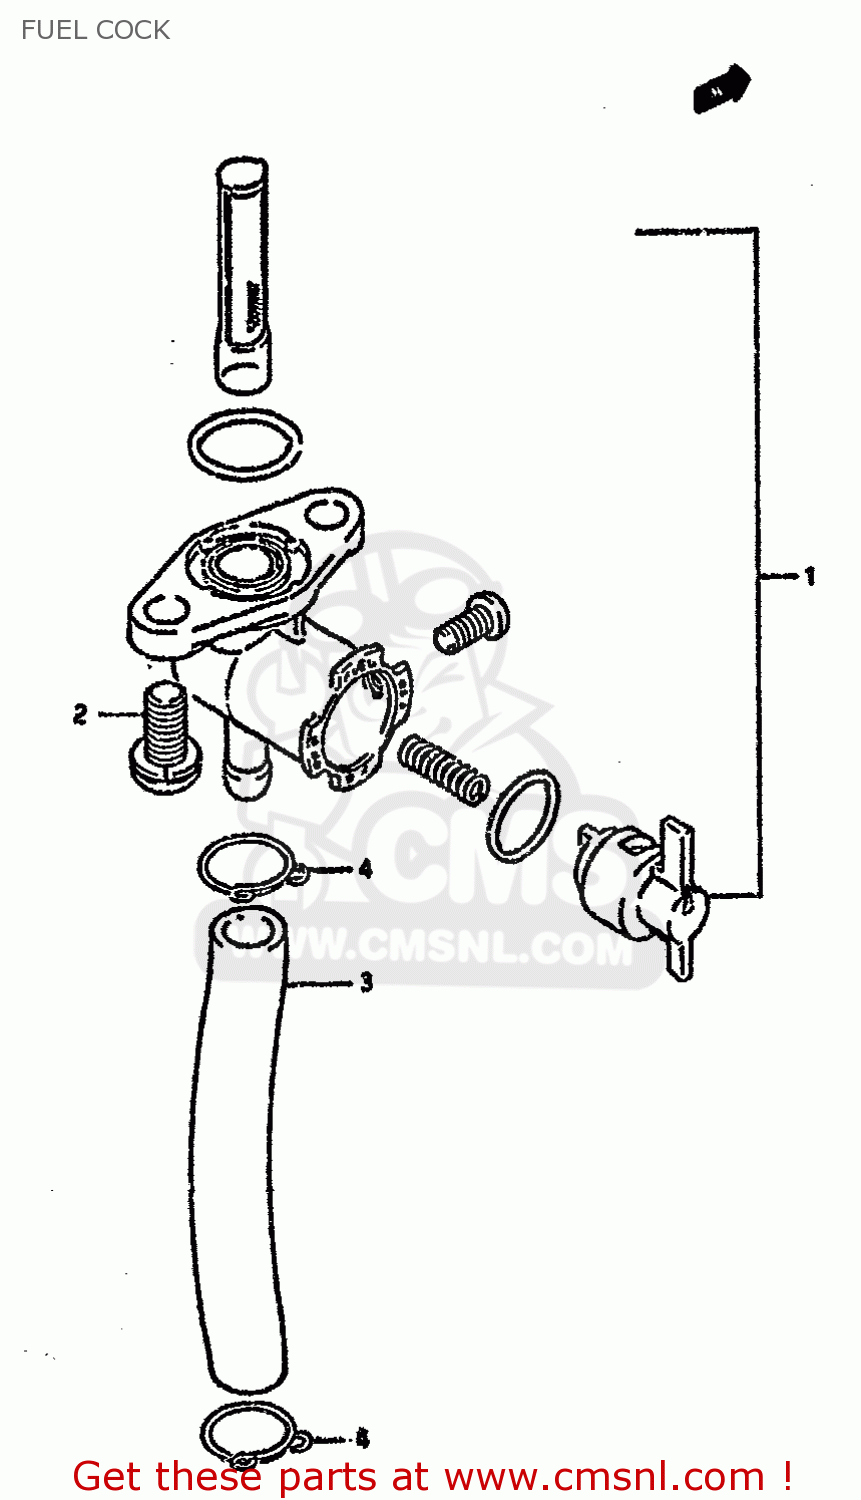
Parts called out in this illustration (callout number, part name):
1	COCK ASSEMBLY,FUEL
2	SCREW
3	HOSE(6.5X11.5X600)
4	CLIP
